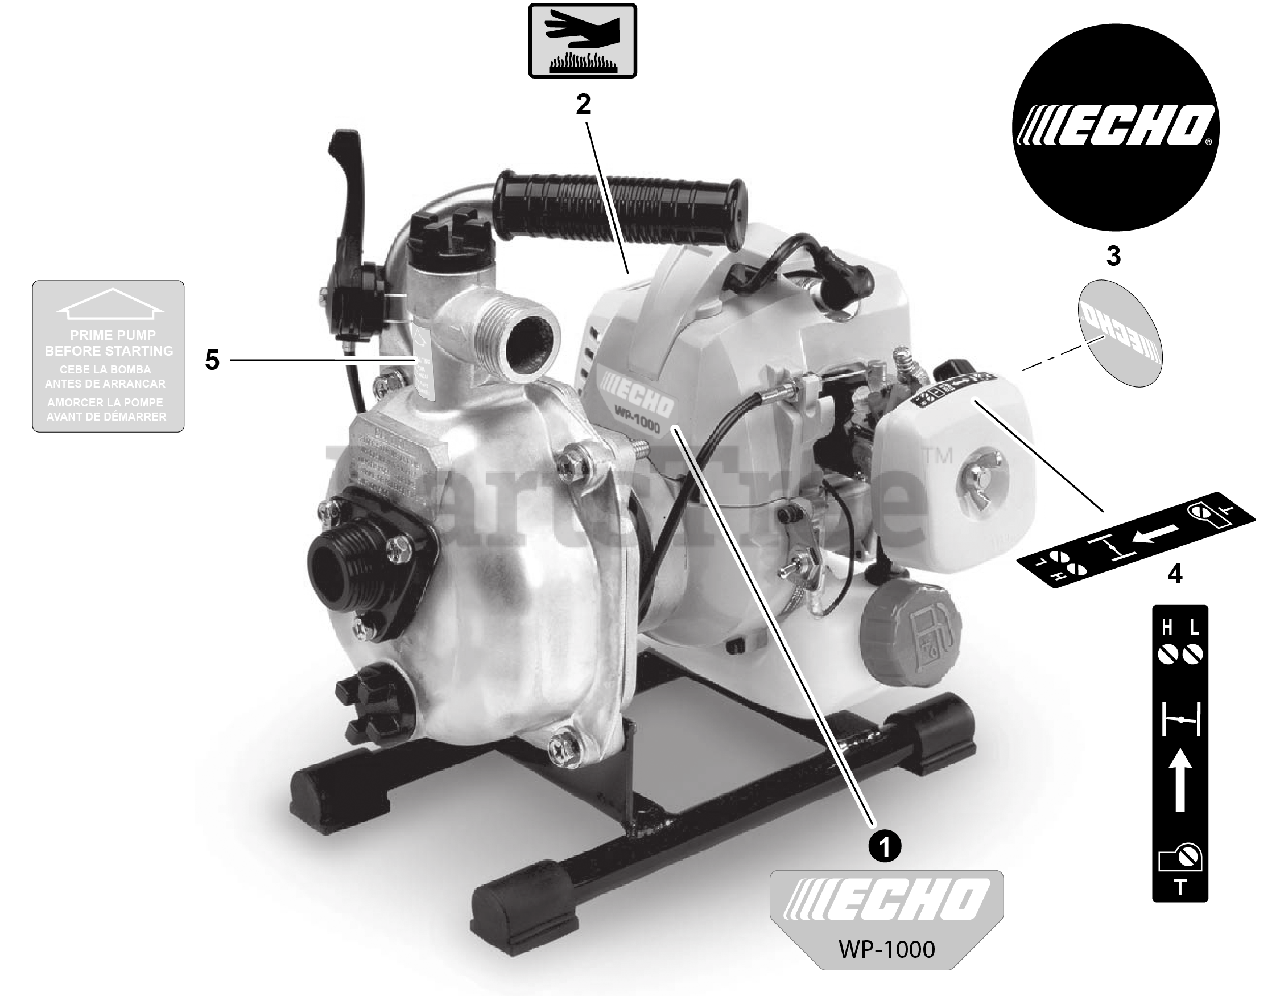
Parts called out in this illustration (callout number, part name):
1	LABEL, MODEL
2	LABEL, CAUTION - HOT
3	LABEL, RECOIL STARTER
4	LABEL, CHOKE
5	LABEL, PUMP
